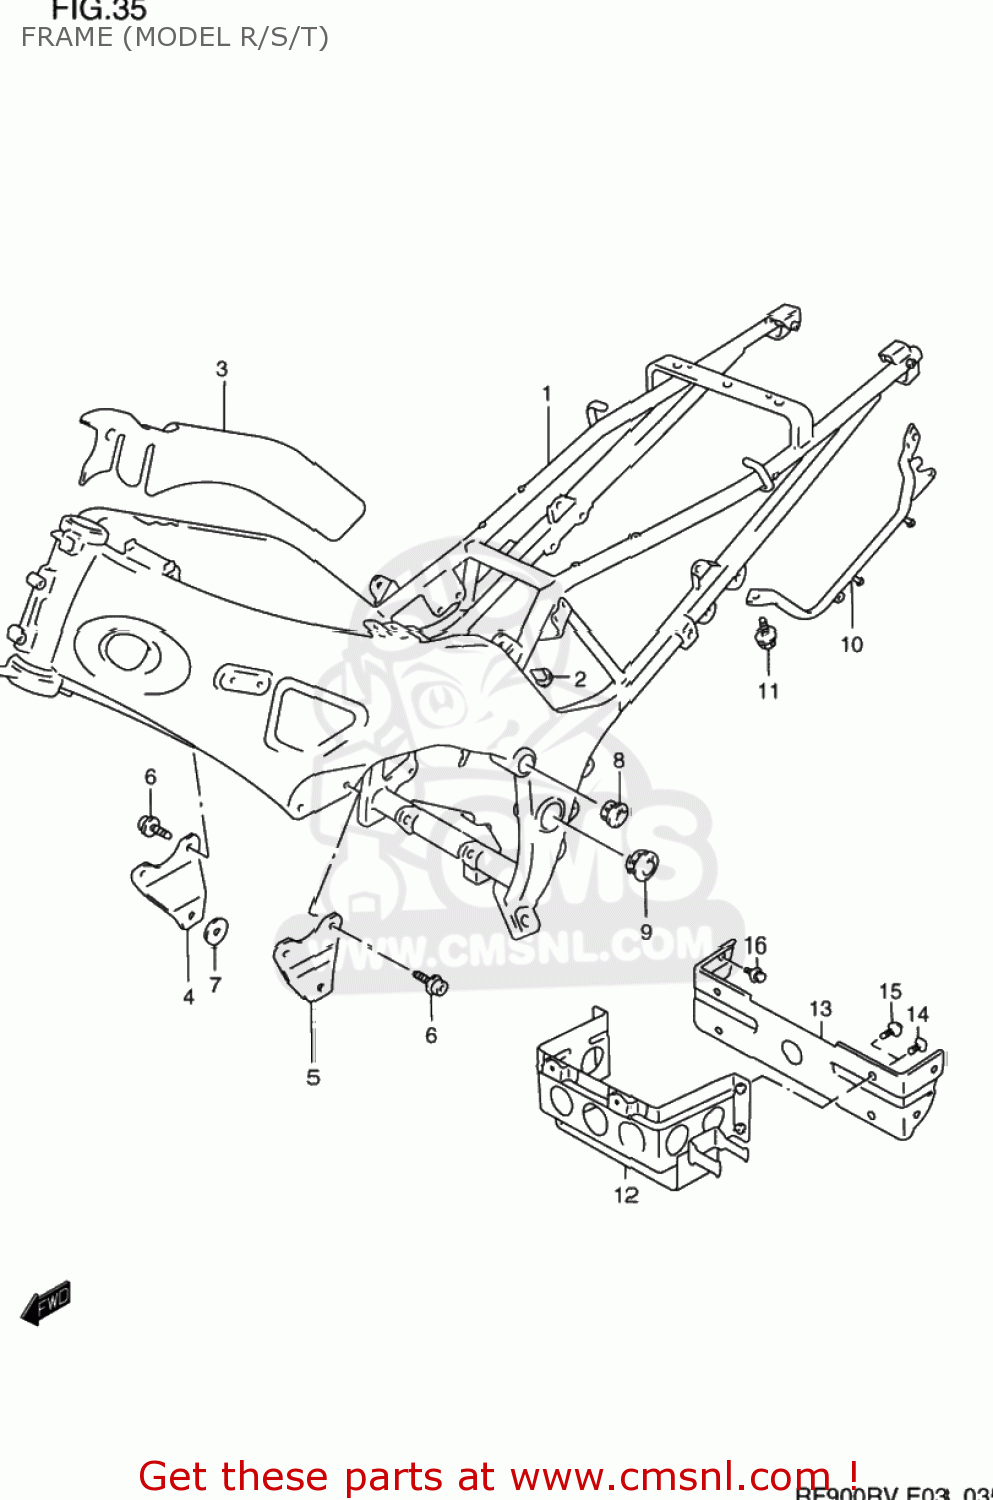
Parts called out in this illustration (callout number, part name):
1	FRAME COMP
2	PLUG(OD:10)
3	SHIELD,FRAME HEAT,L
4	PLATE,ENG MTG,R
5	PLATE,ENG MTG,L
6	BOLT
7	WASHER (10.5X38X1.6)
8	CAP,FRAME BOSS,L
9	CAP,FRAME PIVOT
10	GRIP,RR,L
11	BOLT
12	HOLDER,BATTERY
13	BRACKET,BATTERY HOLDER
14	SCREW 6X12
15	BOLT
16	BOLT
